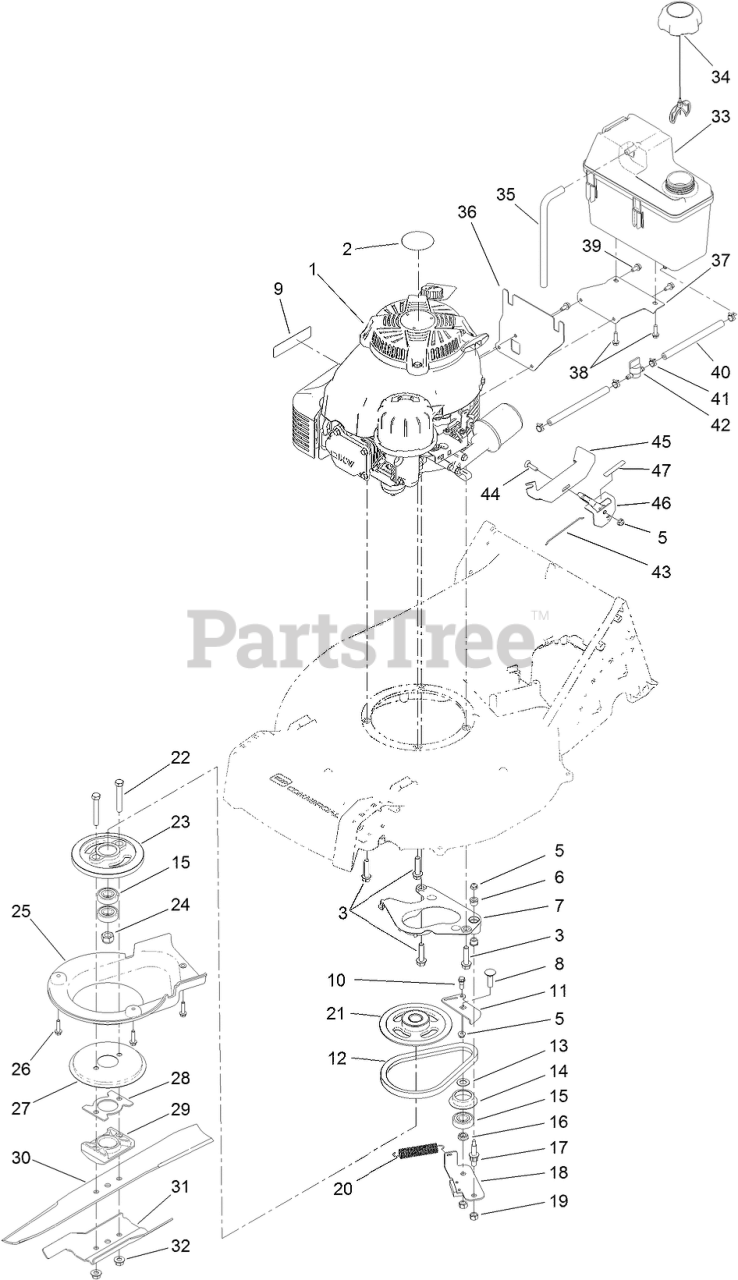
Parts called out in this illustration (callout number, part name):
1	ENGINE-KAWASAKI, FJ180V
3	SCREW-HWH
5	NUT-HF
6	BUSHING-FLANGE
7	PLATE-ANCHOR
8	BOLT-CARR
9	DECAL-ARRESTER, SPARK
10	BOLT-SHOULDER
11	PLATE-GUIDE, BBC
12	BELT
13	WASHER-PLAIN
14	RETAINER-BELT
15	BEARING-BALL
16	SPACER-BEARING
17	BOLT-SHOULDER
18	PLATE-BRAKE
19	NUT-HEX
20	SPRING-TENSION, BRAKE
21	PULLEY
22	SCREW-HH
23	DRUM
24	NUT-HEX
26	SCREW-HWHTF
27	DISC
28	SPACER-DRIVER, BLADE
29	SUPPORT-BLADE
30	BLADE-RECYCLING
31	ACCELERATOR-BLADE
32	NUT-FLANGE, LOCK
33	TANK-FUEL
34	CAP-FUEL
35	HOSE-VENT, CANISTER
36	BRACKET-TANK, MOUNTING
37	BRACKET-TANK, SUPPORT
38	SCREW-HWH
39	SCREW-HWH
40	HOSE-FUEL
41	CLAMP-HOSE
42	VALVE-FUEL
43	WIRE-CONTROL
44	SCREW-CARR
45	BRACKET-MOUNT, THROTTLE
46	CONTROL-THROTTLE
47	DECAL-THROTTLE, CHOKE
